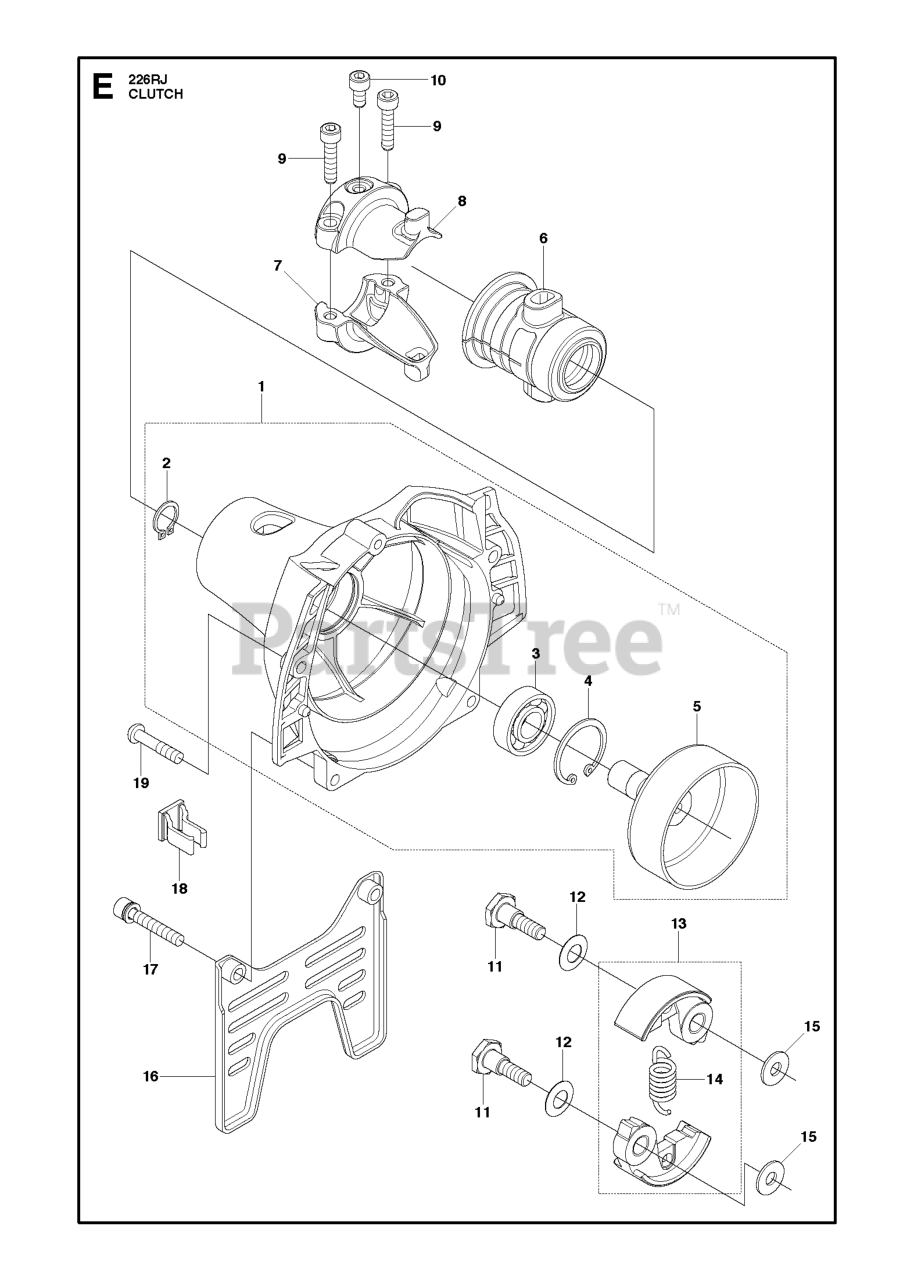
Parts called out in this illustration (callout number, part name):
1	HOUSING-A (RPLS T170231100)
2	RING
3	BEARING
4	RING
5	DRUM (RPLS 481031120-22)
7	BRACKET (B)
8	BRACKET (A) (RPLS T170031211)
9	BOLT
10	BOLT
14	SPRING
